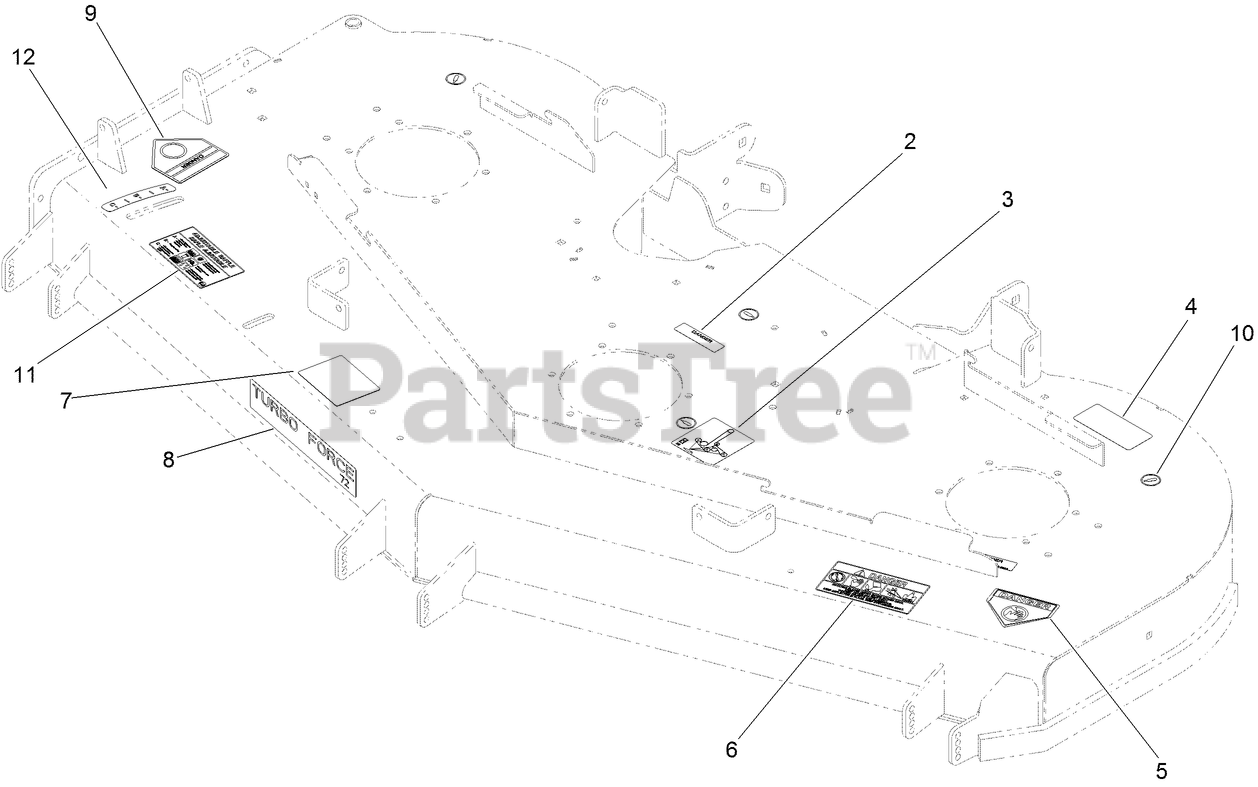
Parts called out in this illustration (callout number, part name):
2	DECAL-COVER, MISSING
3	DECAL-ROUTING, DECK BELT
4	DECAL-TORQUE
5	DECAL-DANGER
6	DECAL-DANGER, THROWN OBJECT
7	DECAL-SCALP, ANTI
9	DECAL-DANGER
10	DECAL-GREASE
11	DECAL-ADJUSTMENT, BAFFLE
12	DECAL-SETTING, BAFFLE
